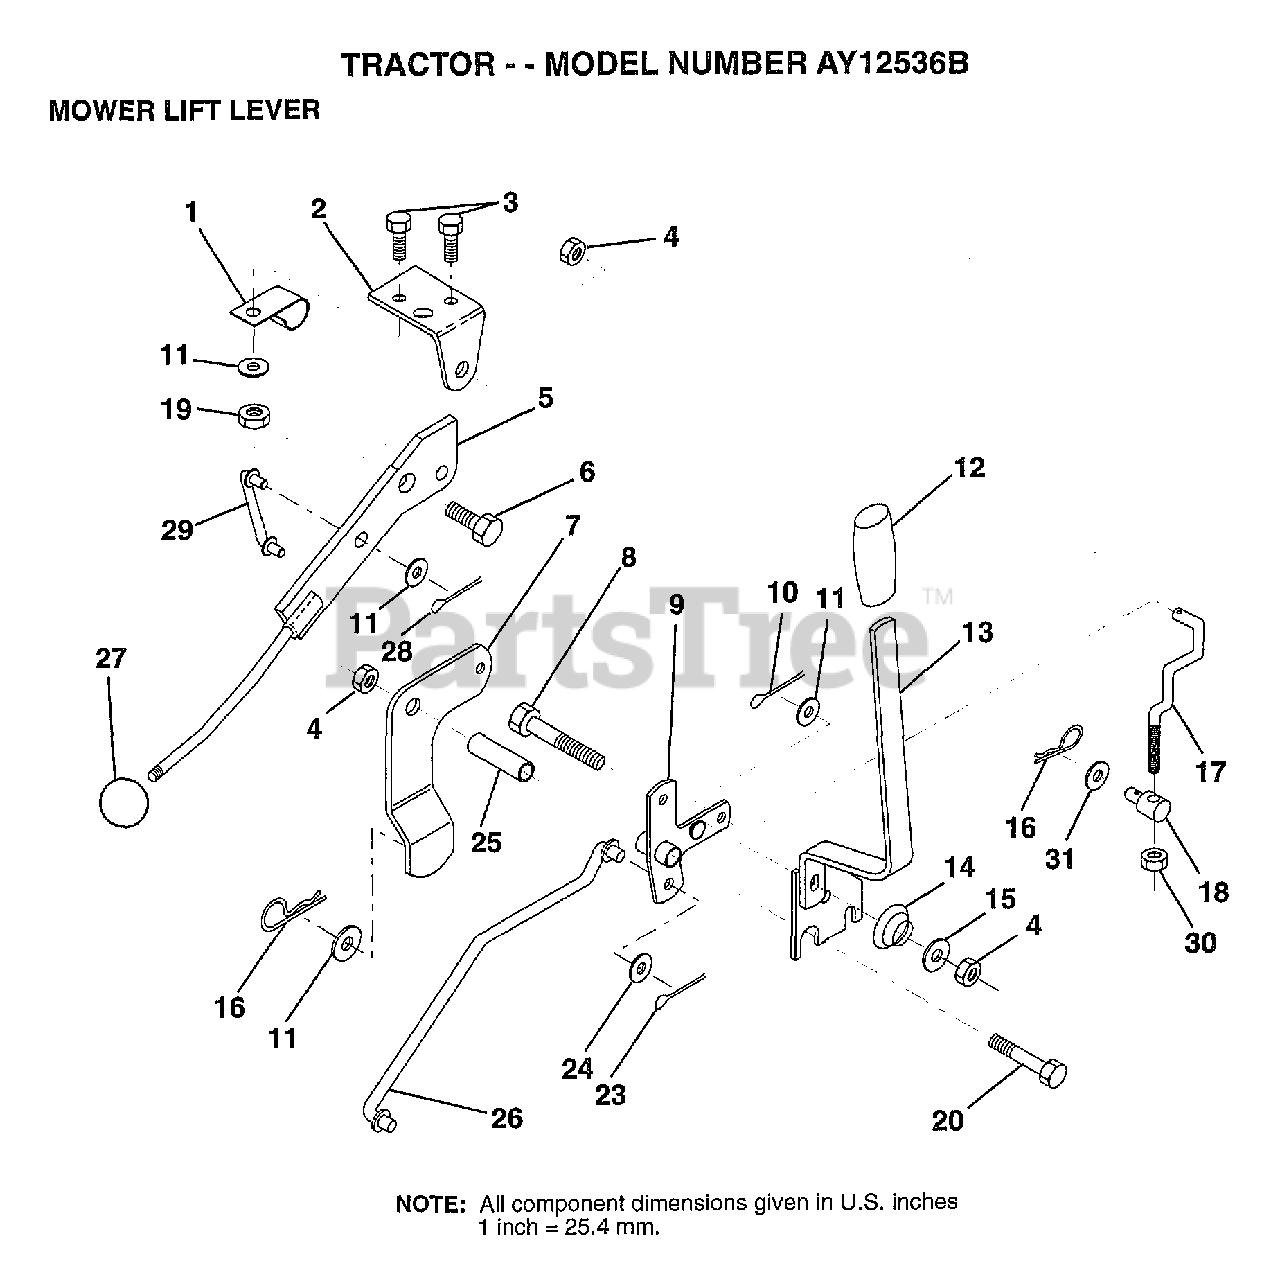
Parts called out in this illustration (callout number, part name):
1	"CLIP,INSULATOR"
2	BRKT CLUTCH
3	BOLT HXHD FIN
5	LEVER.ASM.CLUTCH
6	"BOLT, SHOULDER LT"
7	MWR CLUTCH ARM AS
8	BOLT
9	"BELLCRANK,LIFT"
10	COTTER PIN
11	WASHER
13	HANDLE.ASM.LIFT
14	SPRING COMPRESSIO
15	WASHER T
16	SPRING.RETAINER
17	"LINK,LIFT FRT"
18	TRUNION ADJ
20	BOLT
23	PIN COTTER 1/8
25	TUBE SPACER
26	ROD LIFT MOWER
27	KNOB T(3/8 HOLE)
29	CLUTCH LINK
30	NUT
31	WASHER
